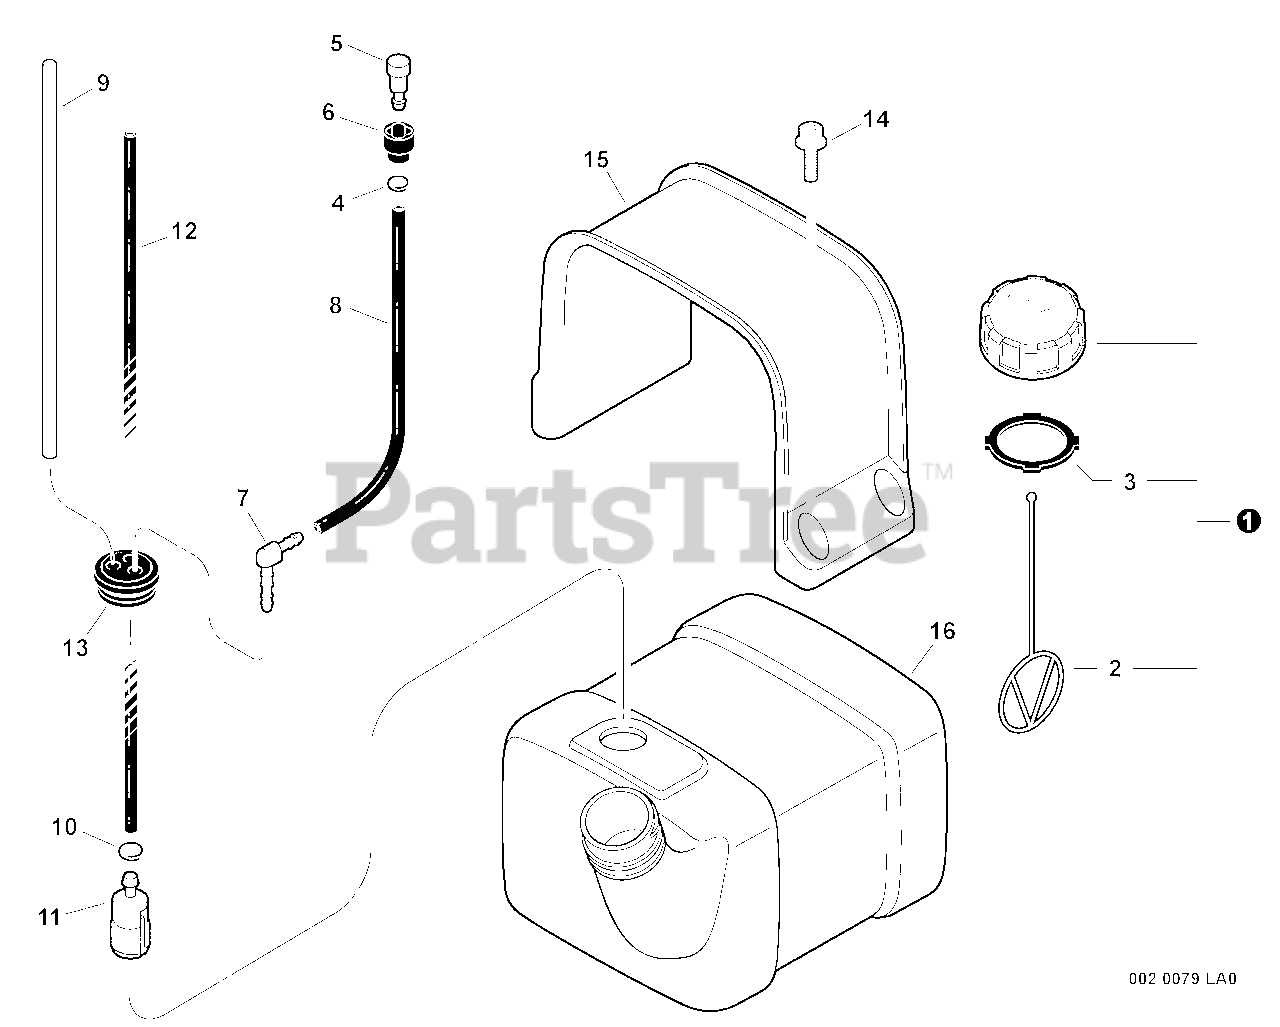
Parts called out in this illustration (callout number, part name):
1	CAP ASSY - ORANGE
2	CONNECTOR, CAP
3	GASKET, CAP
4	CLIP - 6.5
5	VENT, FUEL TANK
6	COVER, VENT
7	CONNECTOR, PIPE
8	PIPE - 3X6X145 -- BLACK
9	PIPE - 3X6X145 -- CLEAR
10	CLIP - 6.5
11	FILTER, FUEL
12	PIPE - 3X6X230 -- BLACK
13	GROMMET
14	SCREW - 5X16
15	COVER, FUEL TANK
16	TANK, FUEL
